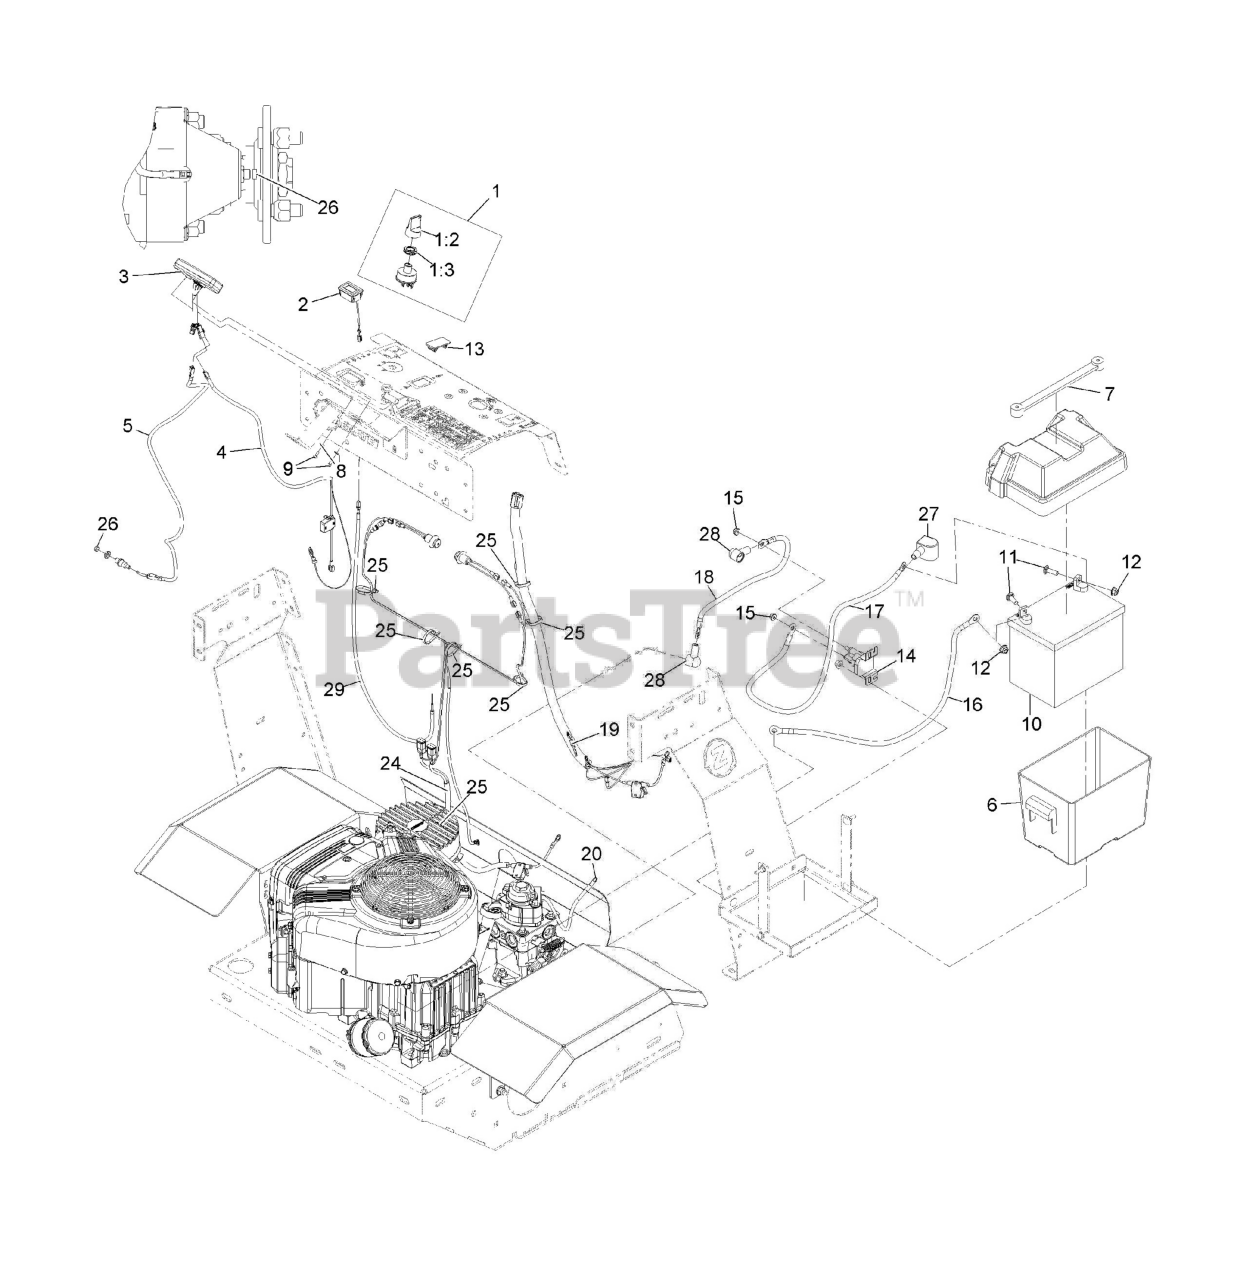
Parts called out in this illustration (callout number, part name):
1	ASM-SWITCH, KEY
1:2	KEY-UMBRELLA
1:3	NUT-SWITCH, KEY
2	METER-TACH/HOUR
3	HEAD ONLY, STRIKER
4	HARNESS-STRIKER
5	Cable-Trail Tech, Sensor
6	BATTERY BOX ASM
7	BUNGEE (TARP STRAP)
8	WASHER-FLAT
9	SCREW-HSH
10	Battery (340 CCA, Wet)
11	SCREW-CARR
12	NUT-HF, NI
13	PLUG-HOLE
14	Solenoid-Starter
16	CABLE-GROUND
17	28" RED BATTERY CABLE
18	CABLE-POSITIVE
19	WIRING HARNESS
20	WIRE-SOLENOID
24	HARNESS, KIT, THUMB SWITCH, ZP
25	TIE-CABLE
26	MAGNET, SPEEDOMETER
27	Insulator-Battery
28	INSULATOR-SOLENOID
29	WIRE-TACHOMETER
